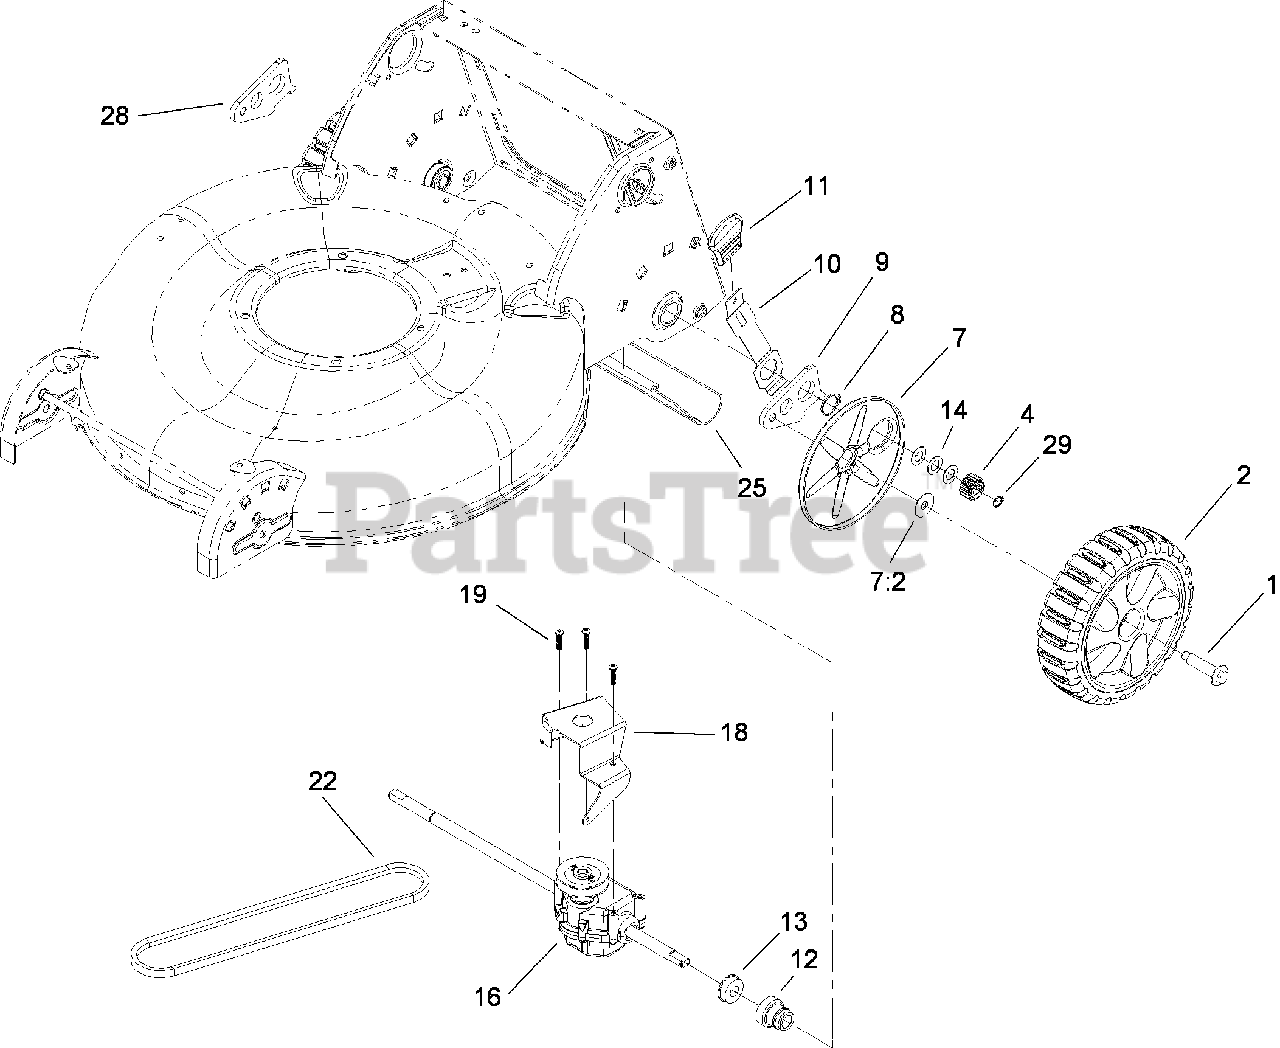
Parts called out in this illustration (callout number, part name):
1	BOLT-SHOULDER
2	REAR WHEEL ASM
4	PINION
7	WHEEL COVER ASM
7:2	WASHER-STEPPED
8	RING-RETAINING
9	ARM-REAR PIVOT, LH
10	ARM-SPRING, REAR
12	RETAINER-BEARING, HOC
13	BEARING-BALL
14	WASHER-PLAIN
16	TRANSMISSION ASM
18	BRACKET-TRANSMISSION
19	SCREW-PLASTITE
25	SHIELD-TRAILING
28	ARM-REAR PIVOT, RH
29	RING-RETAINING
